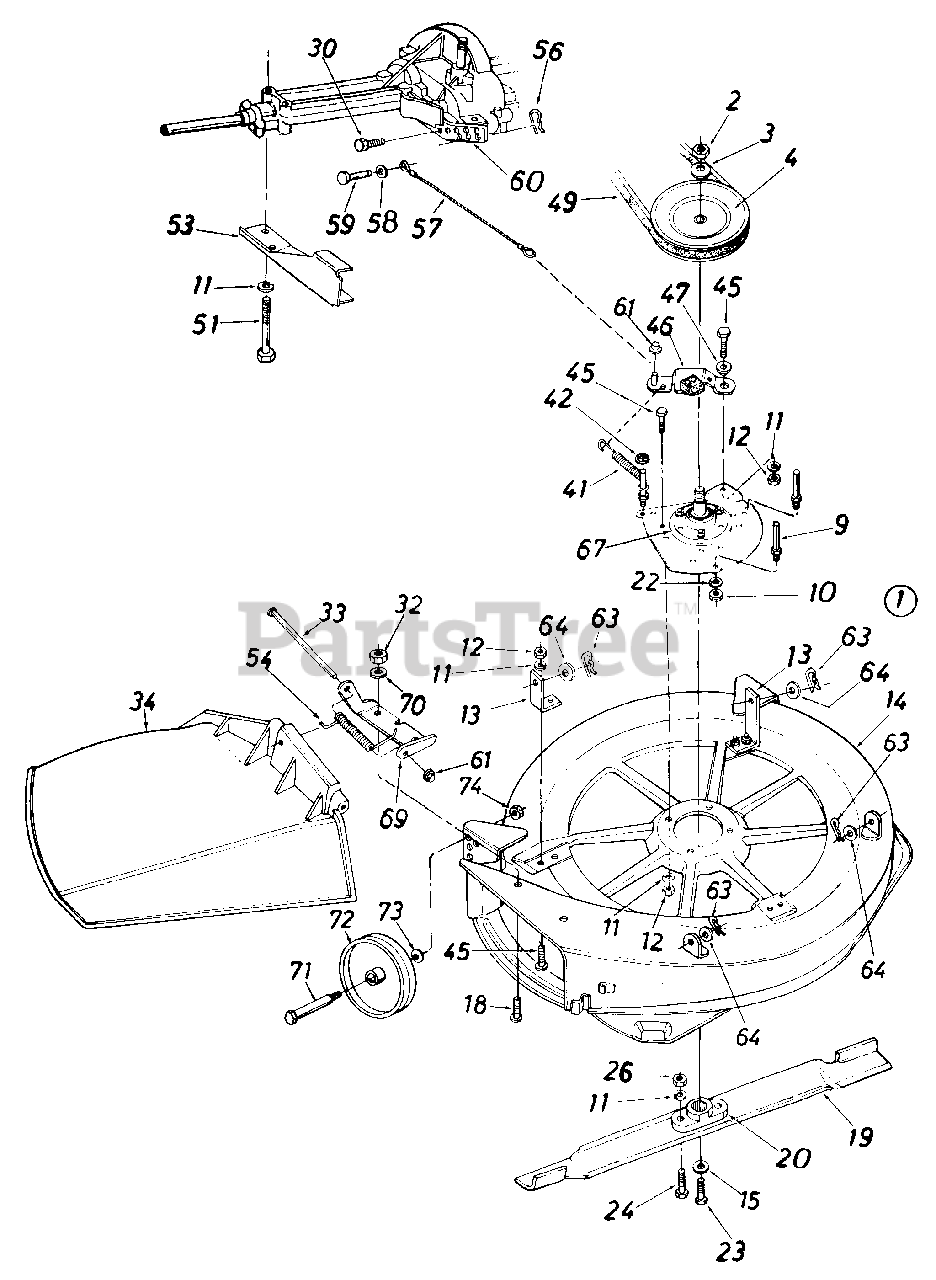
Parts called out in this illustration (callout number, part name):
3	Bell-Wash. .630" I.D. x 1.25"
4	5/8 V-Pulley .75" I.D. x 7"
9	Stud 3/8-16 x 2.75" Lg.
10	Hex Jam Nut 3/8-16 Thd.
11	L-Wash. 5/16" I.D.
12	Hex Nut 5/16-18 Thd.
18	Hex Bolt 1/4-20 x .62" Lg.
19	30" High Lift Blade
20	Blade Adapter
22	L-Wash. 3/8" I.D.
23	Hex Bolt 318-24 x 1.0
24	Hex Bolt 5/16-24 x 1.0" Lg.
26	Hex Nut 5/16-24 Thd.
30	Hex Bolt 1/4-20 x .50" Lg.
32	Hex Nut 1/4-20 Thd.
33	Hinge Pin
34	Chute Ass'y. Comp.
41	Extension Spring
42	Push Speed Nut
45	Hex Bolt 5/16-18 x .75"
46	Blade Brake Brkt. Ass'y.
47	Shoulder Spacer 500" Dia.
49	"V"-Belt
51	Hex Bolt 5/16-18 x 2.75"
56	Int. Cot. Pin 5/16" Dia.
57	Brake Cable 9.75" Lg.
58	Fl-Wash. .281" I.D. x .50"
59	Clevis Pin 1/4" Dia.
60	Lower Inside Belt Guard
61	Cap Speed Nut 1/4" Rod
63	Int. Cotter Pin 1/2" Dia.
64	Fl-Wash. .531" I.D. x .930"
67	Blade Spindle Ass'y. Comp.
69	Hinge Mtg. Brkt.
70	Bell-Wash. 1/4" I.D.
71	Shld. Scr .498" x 1.53" Lg.
72	Deck Wheel
73	Bell-Wash. .38" I.D x .88"
74	Hex L-Nut 3/8-16 Thd.
